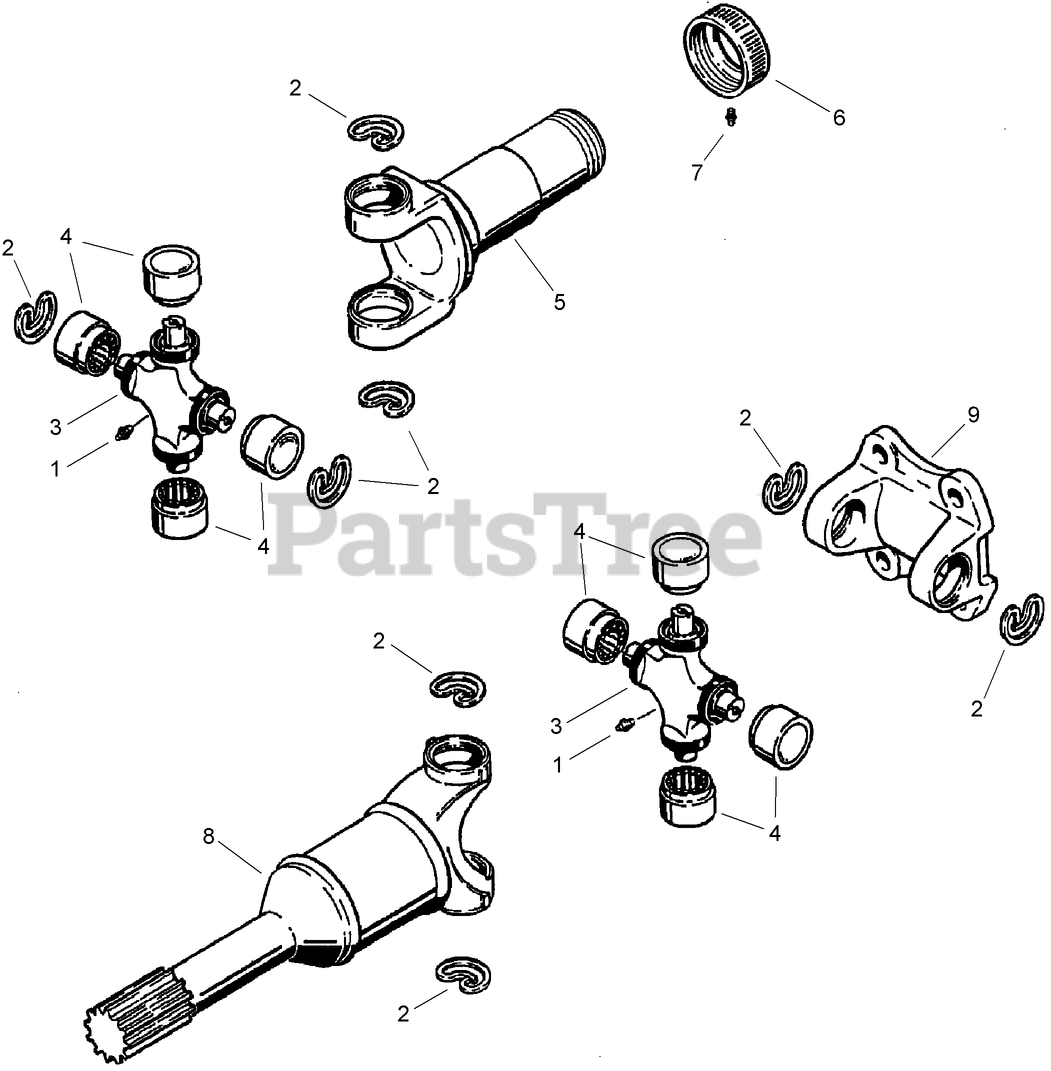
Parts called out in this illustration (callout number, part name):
1	FITTING-LUBE
2	RING-RETAINING
3	JOINT - Universal, Drive Shaft
4	BEARING - Universal Joint
7	FITTING-LUBE
8	DRIVE SHAFT ASM
